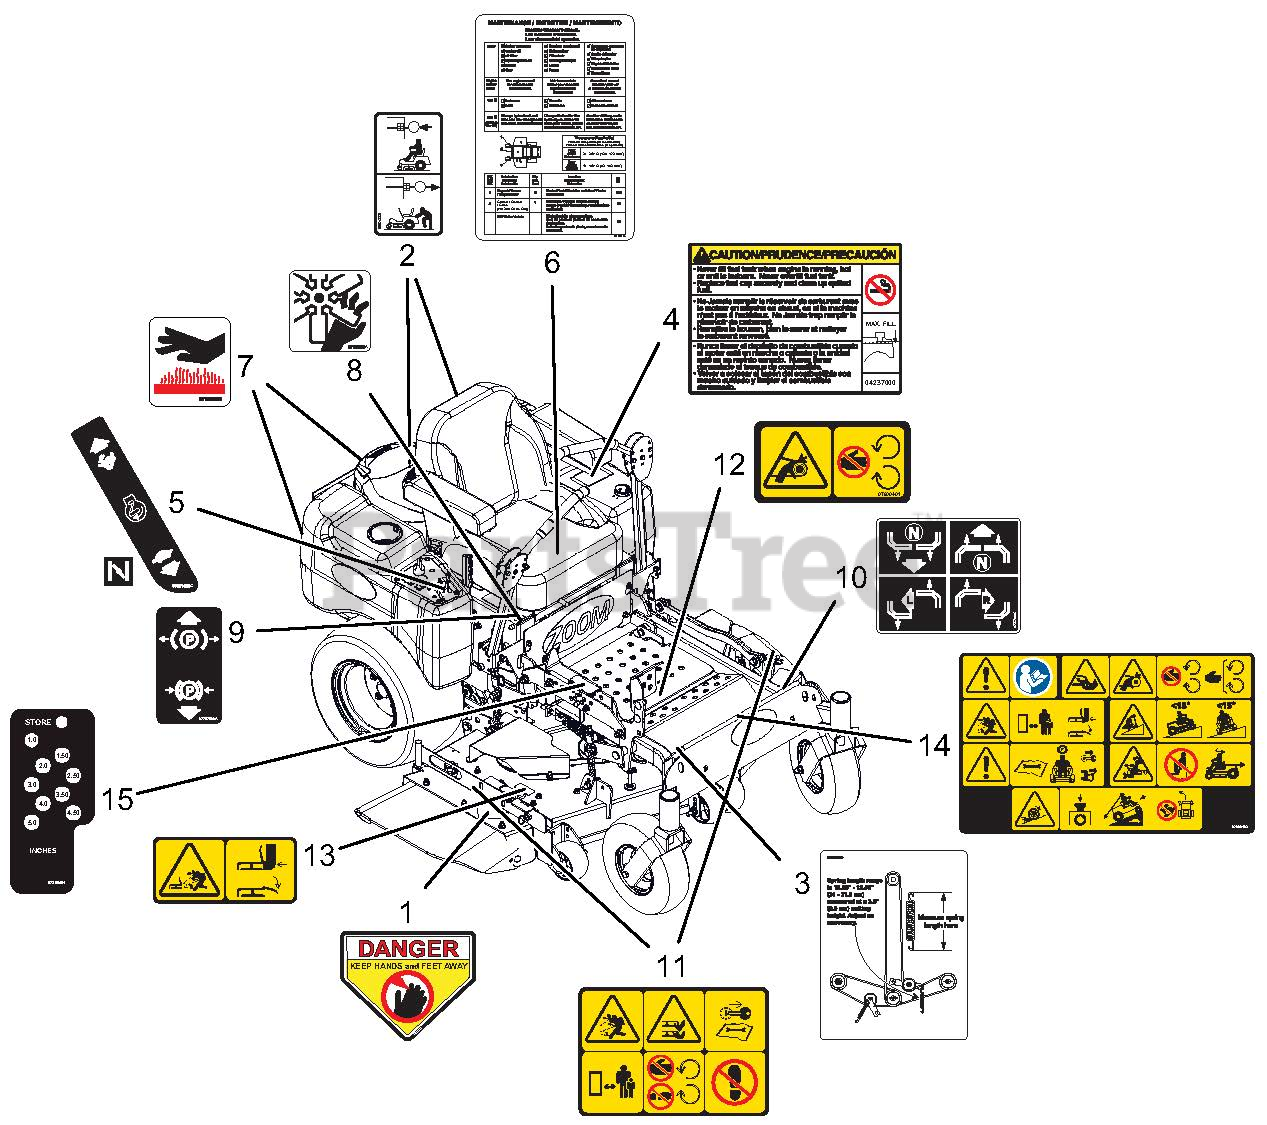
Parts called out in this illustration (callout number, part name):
1	DECAL, DANGER
2	DECAL, TRANSMISSION DISCONNECT
3	DECAL, BELT ROUTING
4	DECAL, FUEL WARNING
5	DECAL, SPEED CONTROL
6	DECAL-MAINTENANCE INSTRUCTIONS
7	DECAL, HOT SURFACE
8	DECAL, DANGER FAN
9	DECAL, PARKING BRAKE LEVER
10	DECAL, INSTRUCTIONAL-STEERING
11	DECAL, SAFETY - MOWER DECK
12	DECAL, SAFETY - GUARDING
13	DECAL, SAFETY - DECK GUARDING
14	DECAL, MAIN SAFETY
15	DECAL, HD HEIGHT OF CUT
